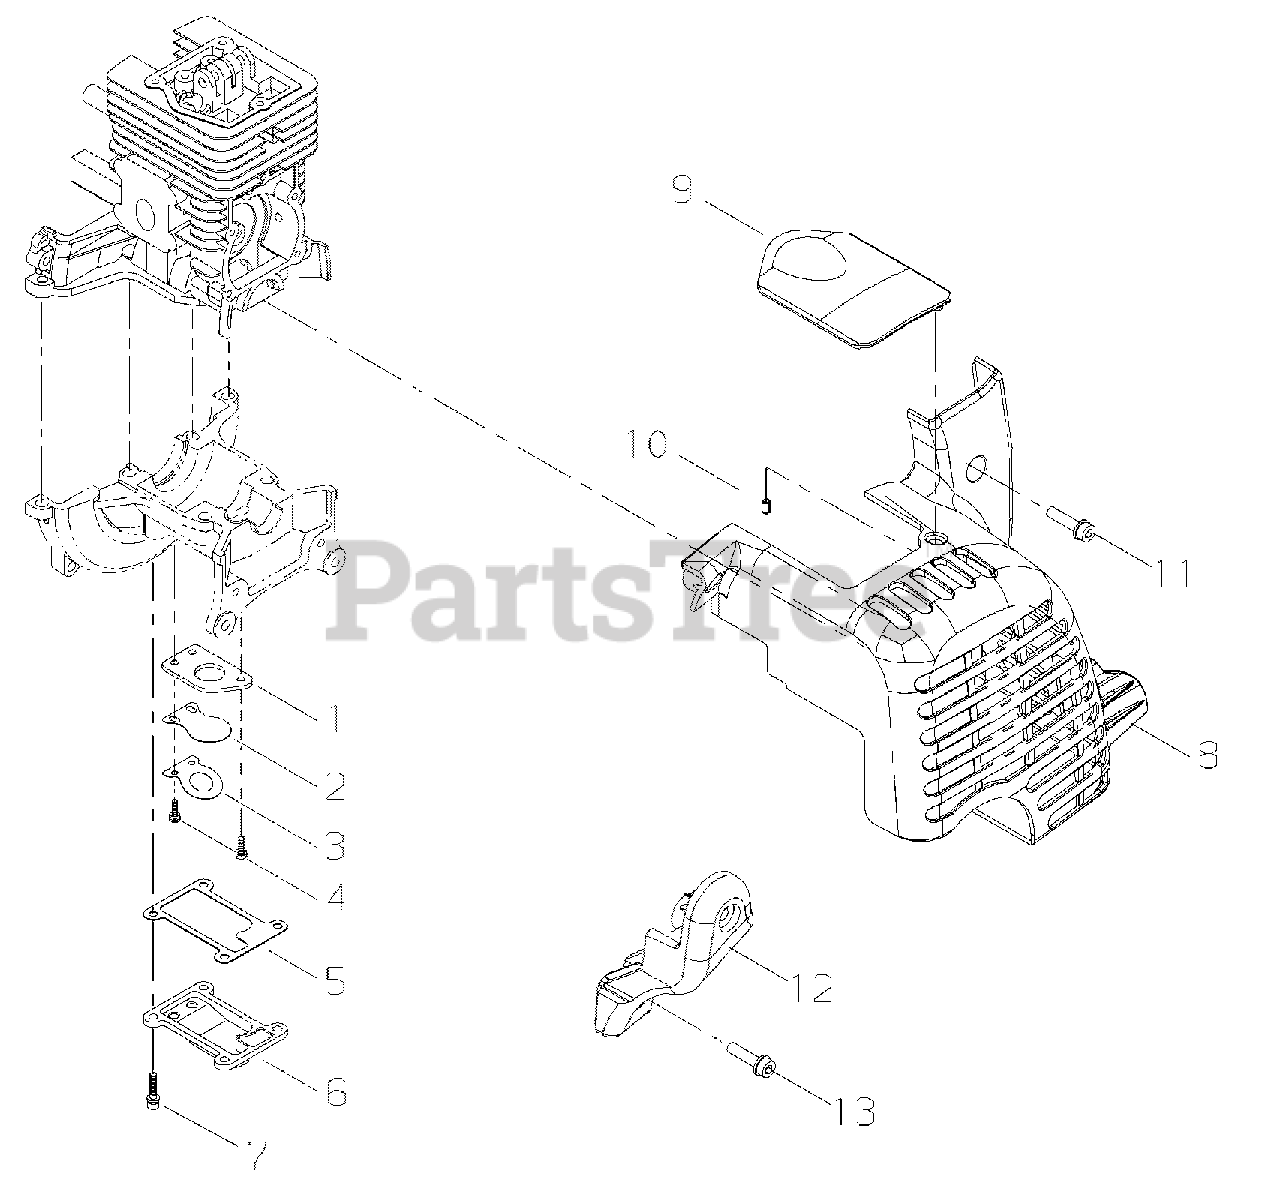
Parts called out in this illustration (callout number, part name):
1	PLATE, REED BACKING
2	VALVE, REED
3	STOP, REED VALVE
4	SCREW - 3X10
5	GASKET, REED VALVE
6	COVER, REED VALVE
7	SCREW - 4X12
8	COVER, ENGINE
9	COVER, SPARK PLUG
10	PIN - 4X8
11	BOLT - 5X20
12	COVER, HANDLE
13	BOLT - 5X20
